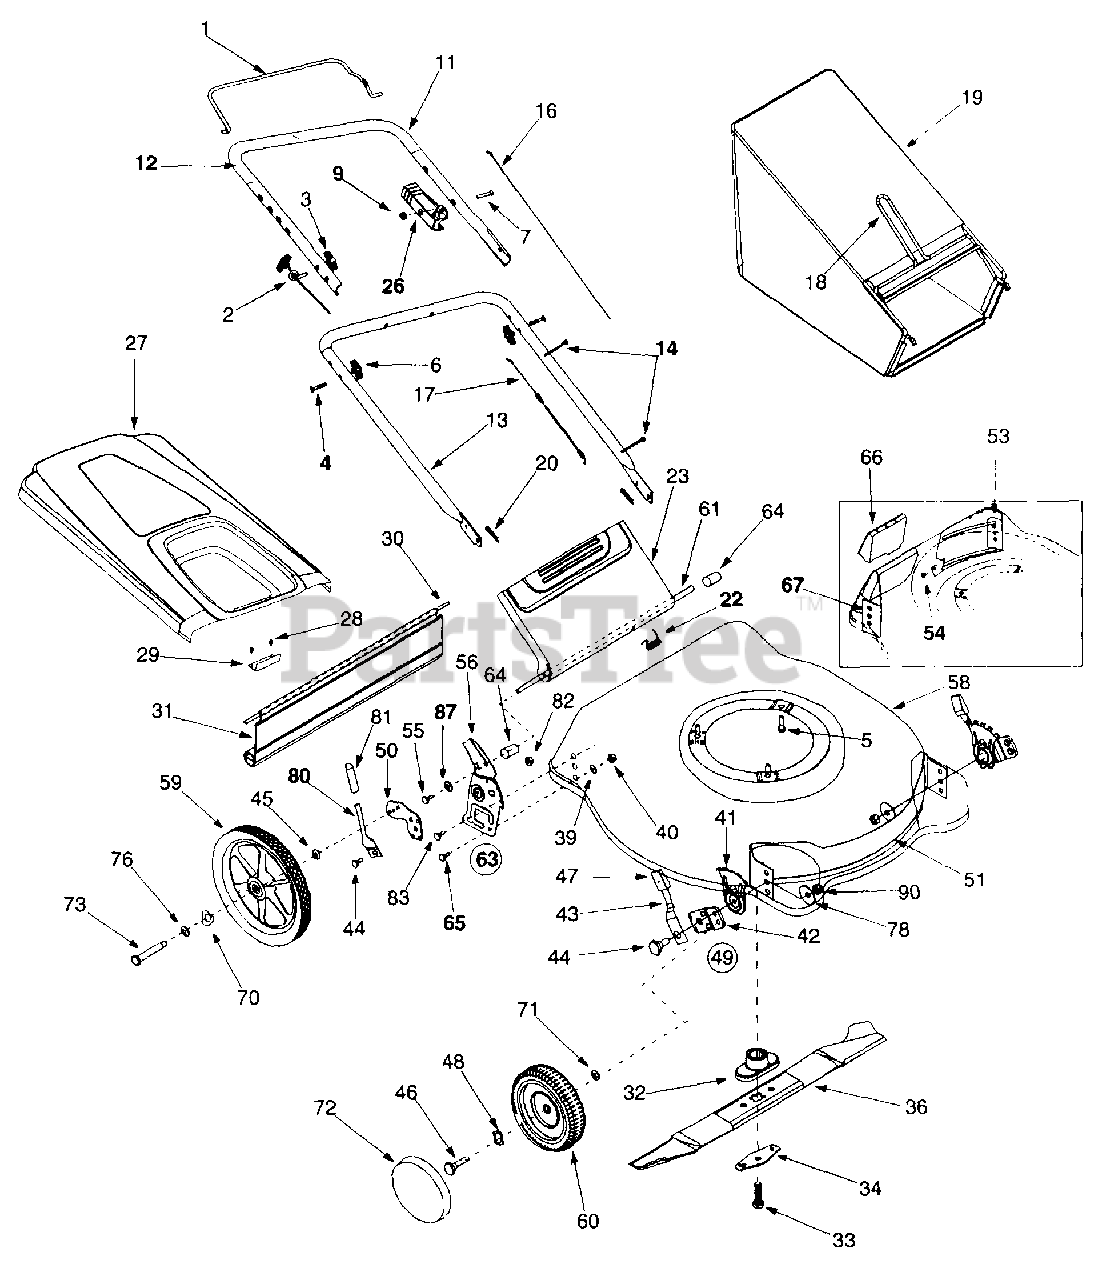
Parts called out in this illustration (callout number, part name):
2	Rope Guide
3	Handle Knob
4	Carriage Bolt 5/16-18 x 2"
5	Hex Washer Screw 3/8-16 x 1.00"
6	Hand Knob
7	C-Sunk Screw 1/4-20 x 1.3"
9	Hex Lock Nut 1/4-20
14	Cable Tie
16	Blade Control Cable - 39"
17	Throttle Cable - 51"
19	Grass Catcher Bag w/o Logo
20	Hairpin Clip
22	Door Spring
27	Hard Top w/ Logo
28	Hex Washer Screw 1/4-20 x .625
31	Rear Flap
32	Blade Adapter
33	Hex Bolt 3/8-24 x 1.5
34	Blade Bell Support
36	21" Mulching Blade
39	Bell Washer .39 I.D. x 1.38 I.D.
40	Hex Nut 3/8-16
41	Height Adj. Plate
43	Front Wheel Spring Lever
44	Shoulder Bolt .5" x .357"
45	Bell Wash. .38" I.D. x .88" O.D.
46	Front Axle Bolt
47	Height Adjuster Knob
48	Wave Washer .510 x .750
49	Height Adjuster Assembly - R.H.
50	Pivot Bar - R.H.
54	Tap Screw 1/4-14 x .625
55	Hew Washer Screw 1/4-20 x .500
60	Front Wheel Assembly 8 x 2
61	Chute Door Pivot Rod
63	Handle Bracket Assembly. - R.H.
64	Spacer .375 O.D. x .50 I.D. x 1.02"
65	Hex Cap Screw 3/8-16 x .75
66	Rear Mulch Plug
70	Wave Washer
71	Spring Washer
72	Hub Cap
73	Rear Axle Bolt
76	Flat Washer
78	Bell Washer
80	Spring Lever, Rear
81	Foam Grip
82	Hex Flange Lock Nut 3/8-16
83	Hex Washer Screw 1/4-14 x .625
87	Bell Washer .265 x .75 x .062
90	Hex Nut 3/8-16
